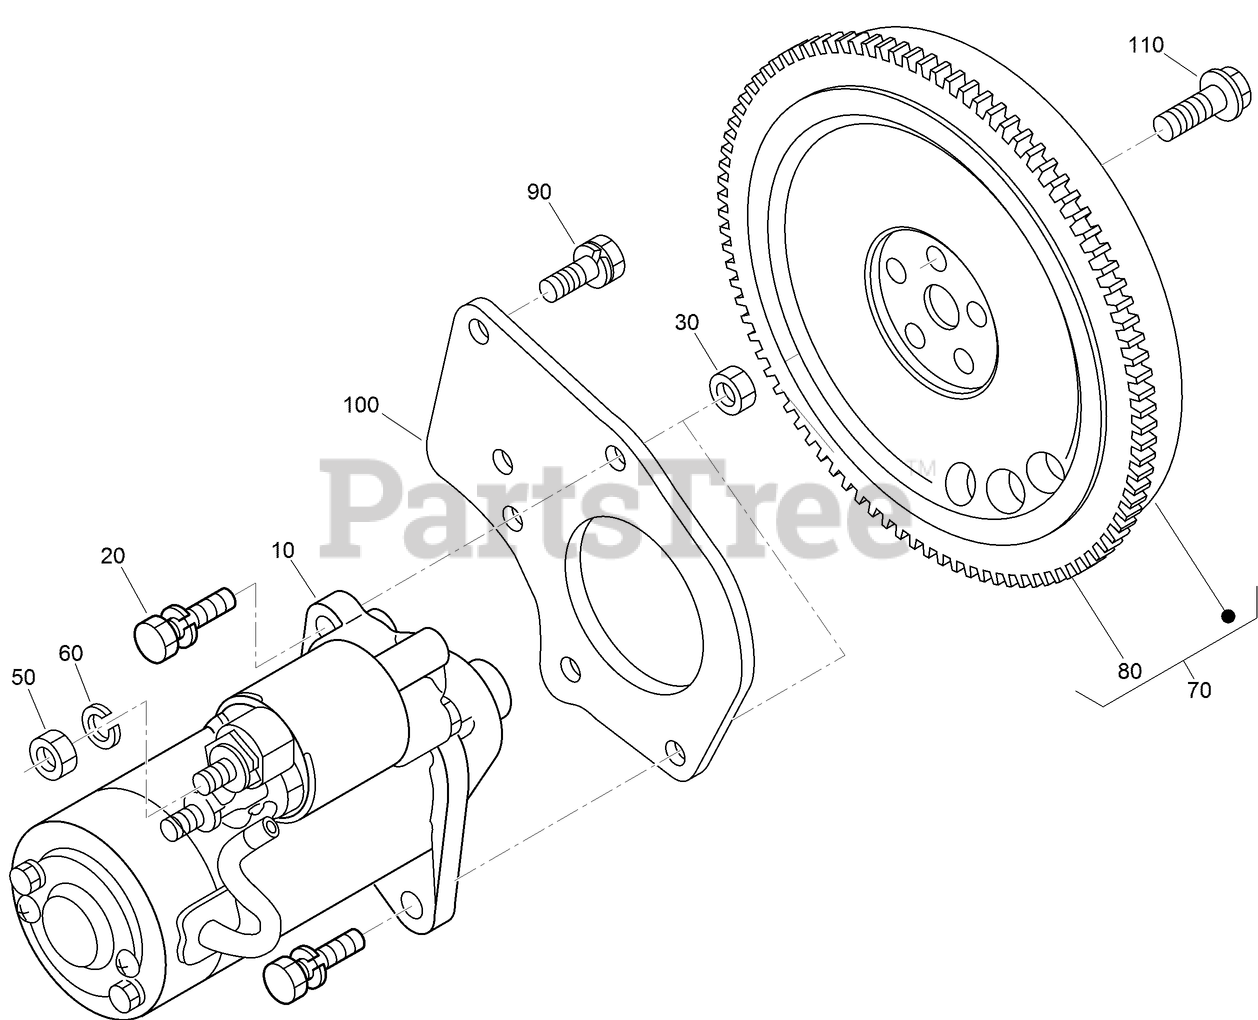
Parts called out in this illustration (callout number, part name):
10	STARTER ASM
60	WASHER-SPRING
70	FLYWHEEL ASM
80	GEAR-RING
90	BOLT-FLYWHEEL
100	PLATE-END, REAR
